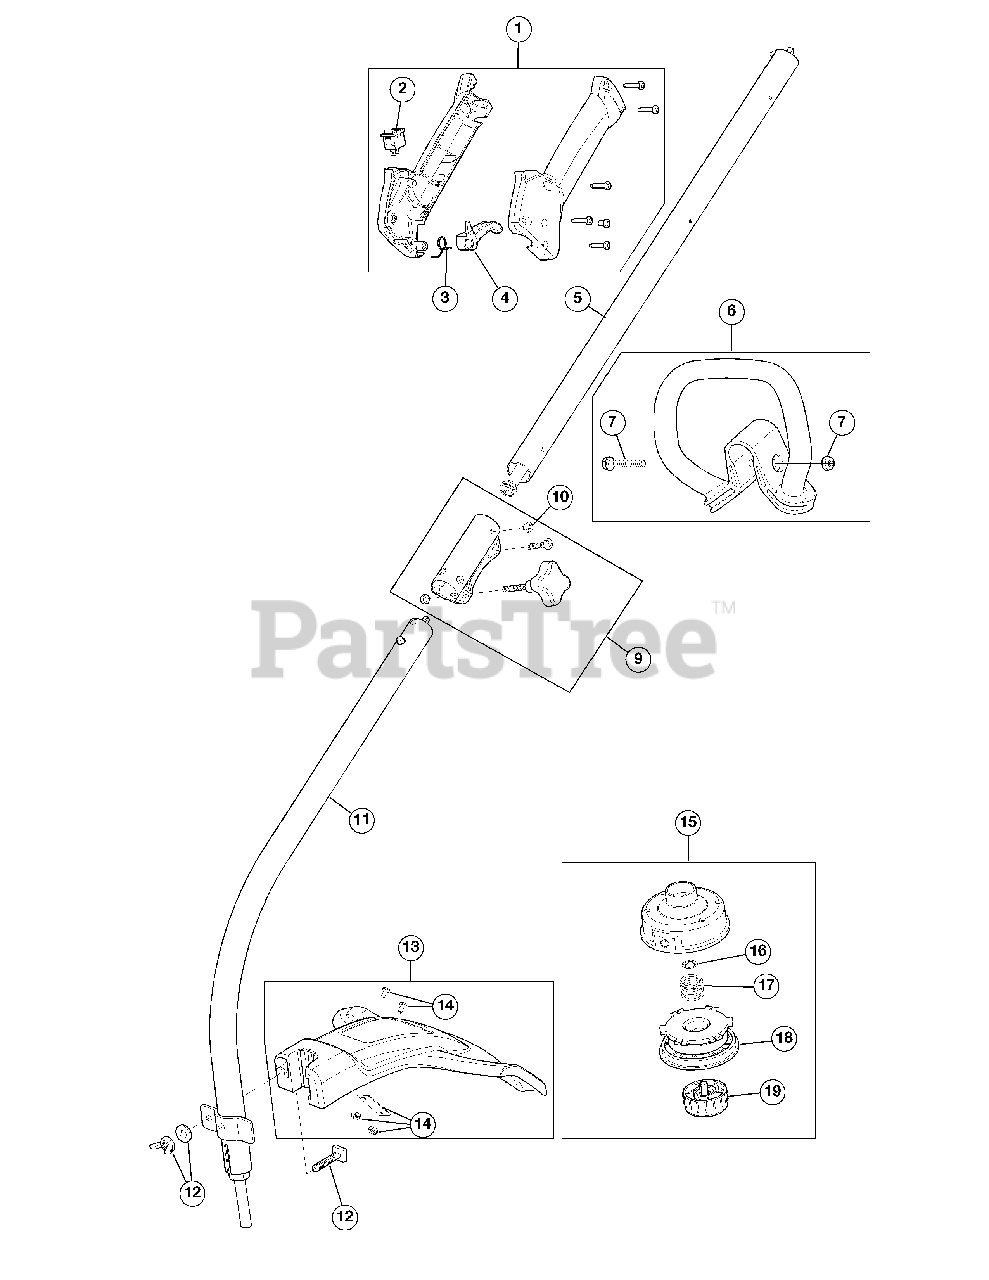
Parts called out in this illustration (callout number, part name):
1	Throttle Housing Assembly (Incl. 2 - 4)
2	Switch Assembly
3	Throttle Trigger Spring
4	Throttle Trigger
5	Upper Shaft Housing Assembly
6	D-Handle (Incl. 7)
7	D-Handle Bolt
8	Split Boom Coupler (Incl. 9)
9	Anti-Rotation Screw
11	Lower Shaft Housing Assembly
12	Shield Mounting Hardware
13	Shield Assembly (Incl. 14)
14	Blade Assembly
15	Outer Spool Assembly (Incl. 16)
16	Retainer
18	Inner Reel
19	Bump Head Knob Assembly
